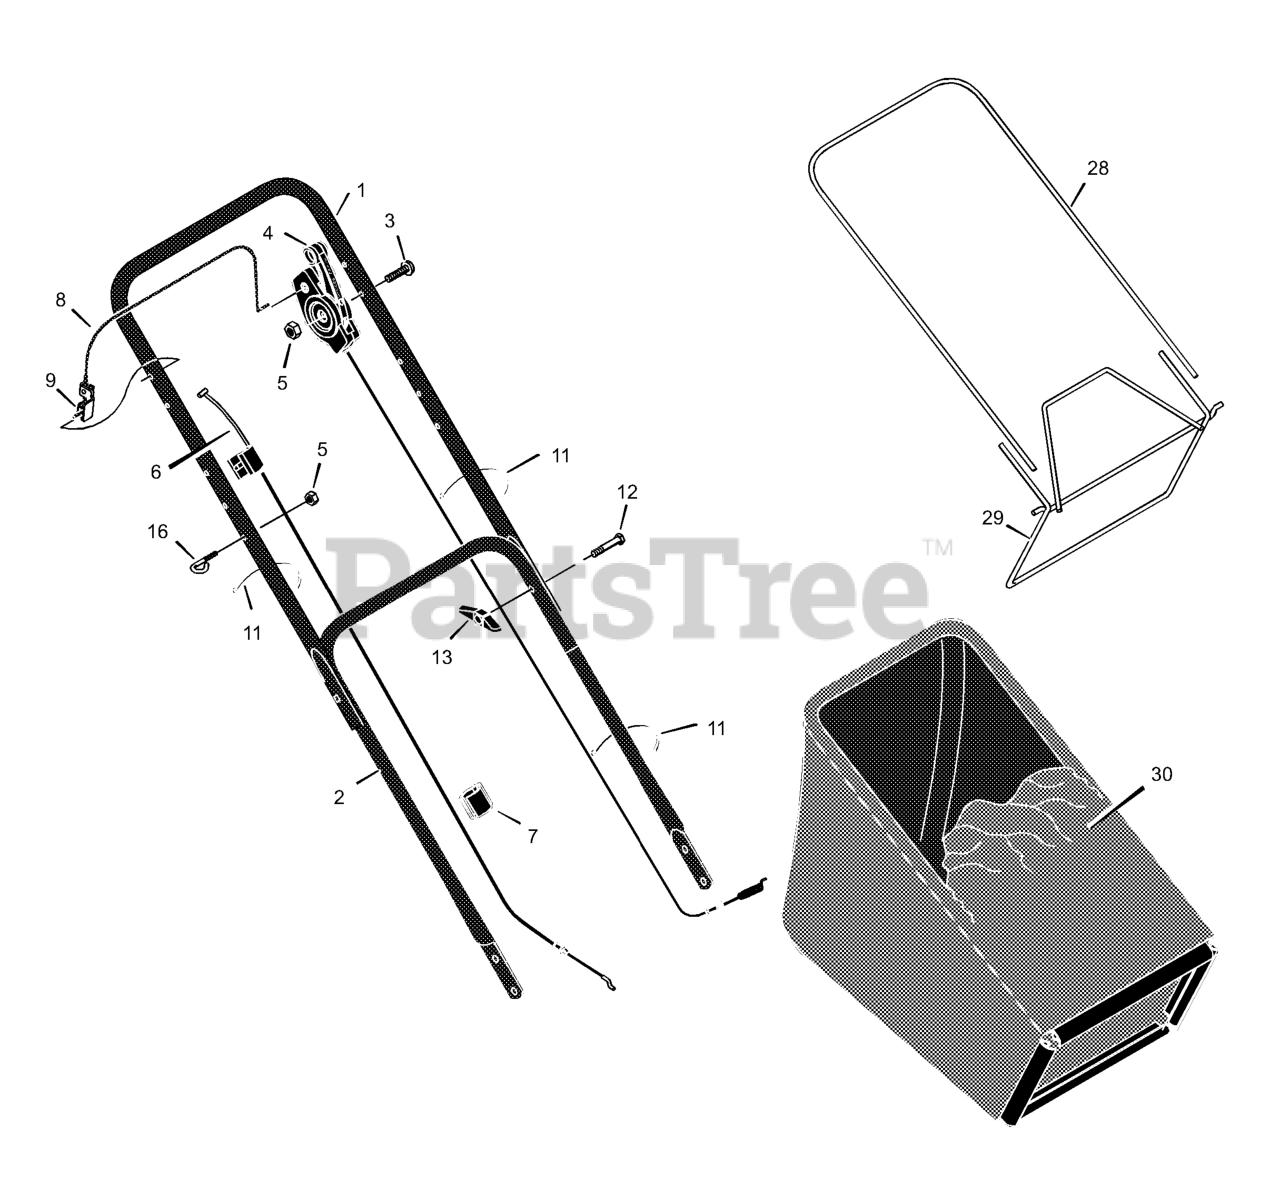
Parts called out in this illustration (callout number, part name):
1	Handle, Upper (Gray)
2	Handle, Lower (Gray)
4	Control, Drive
5	Locknut
6	Cable, Stop
7	Fastener, Cable
8	Engine Stop Lever
9	Bracket, Stop Lever
11	Fastener, Cable
13	Knob
16	Guide, Rope
28	Frame, Top
29	Frame Assembly
30	Bag, Cloth
